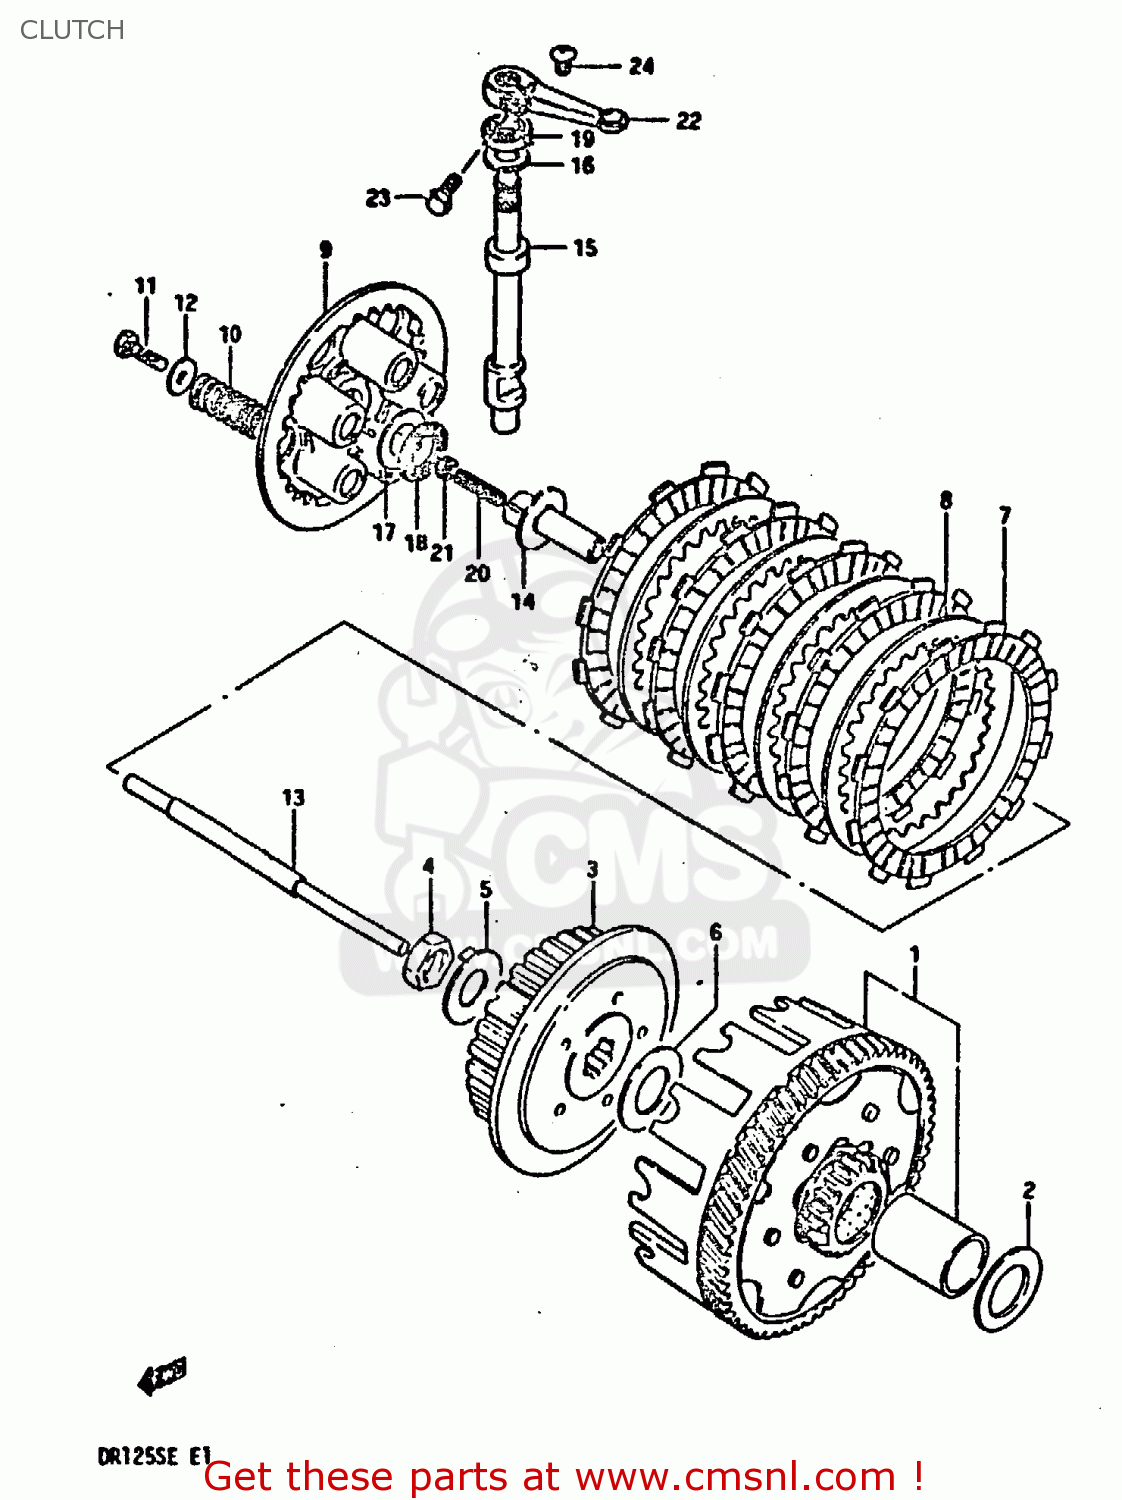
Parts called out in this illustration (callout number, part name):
1	GEAR ASSEMBLY,PRIMARY DRIVE
2	WASHER
3	HUB,CLUTCH SLEEVE
4	NUT
5	WASHER
6	WASHER
7	PLATE,CLUTCH DRIVE
8	PLATE,CLUTCH DRIVEN (NAS)
9	PLATE,CLUTCH PRESSURE
10	SPRING
11	BOLT(5X16)
12	WASHER (5.5X16X1.2)
13	ROD,CLUTCH PUSH
14	PIECE,CLUTCH PUSH
15	CAMSHAFT,CLUTCH RELEASE
16	WASHER,THRUST
17	WASHER
18	BEARING(15X28X2)
19	OIL SEAL
20	SCREW(6X25)
21	NUT 6MM
22	ARM,CLUTCH RELEASE
23	BOLT, UPPER
24	SCREW
